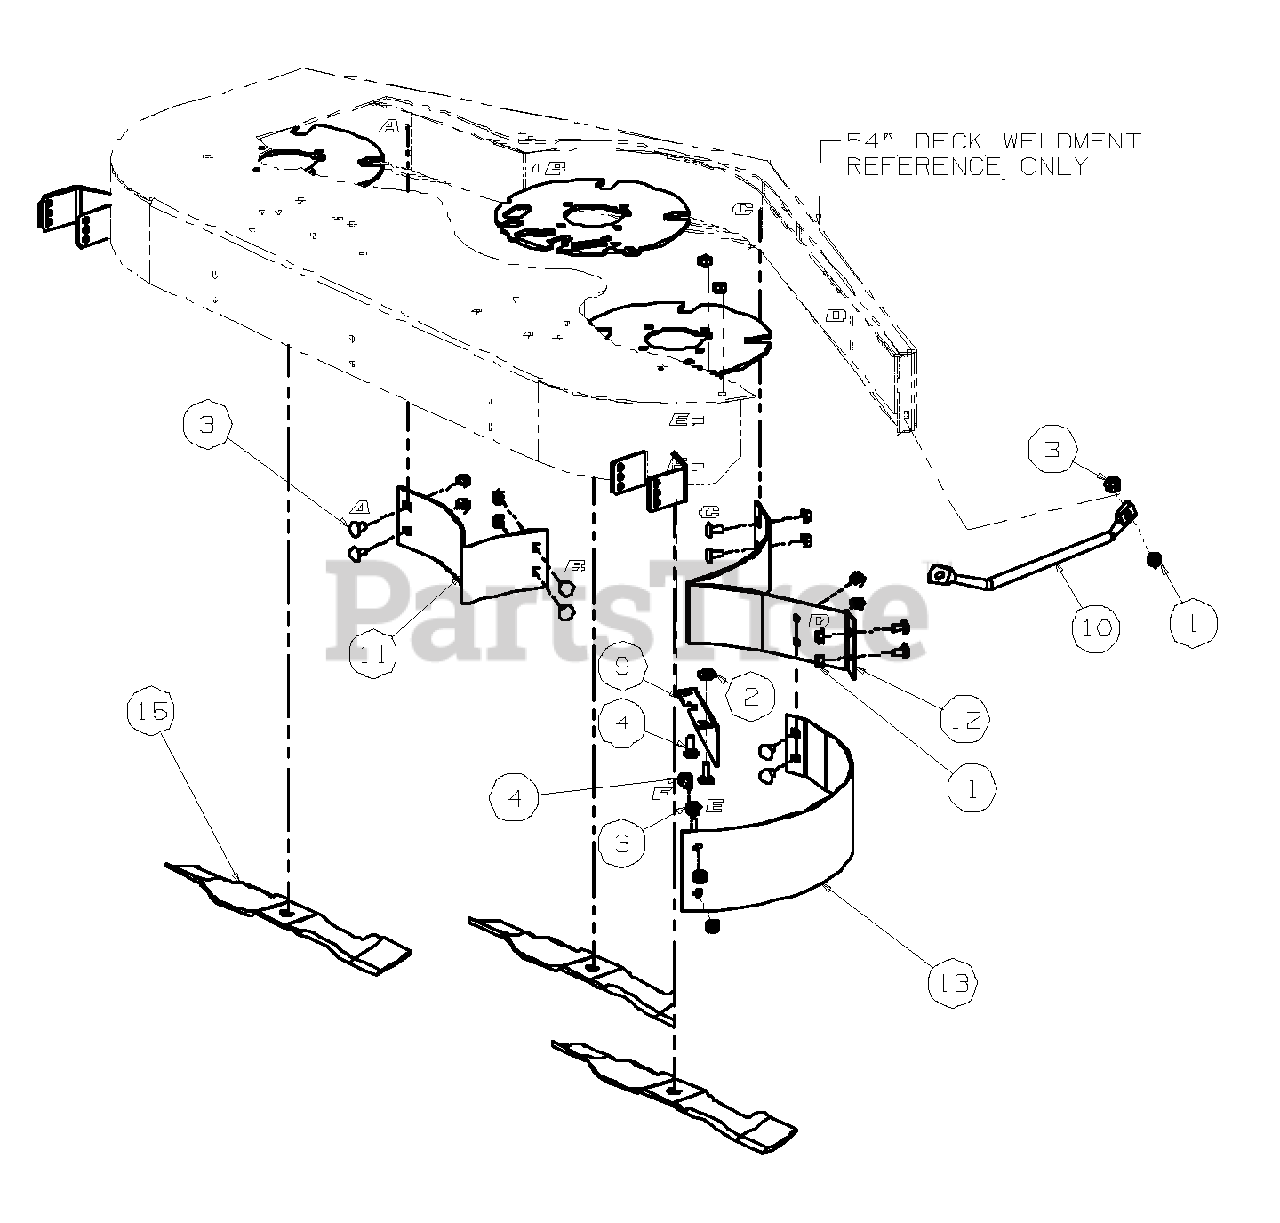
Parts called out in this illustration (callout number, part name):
1	NUT:HEX 3/8-16 FLG LOCK
2	WASHER:IDLER
3	BOLT:CARR 3/8-16 X .75 LG
4	BOLT:CARR 3/8-16 X 1.0 LG
9	BRKT:CHUTE:FAB DECK
10	GUARD:FINGER:FAB DECK
11	BFL:MULCH:FAB 54 LH
12	BFL:MULCH:FAB 54 CENTER
13	BFL:MULCH:FAB 54 RH
15	BLADE:19.0:MULCH:0.756 ID
